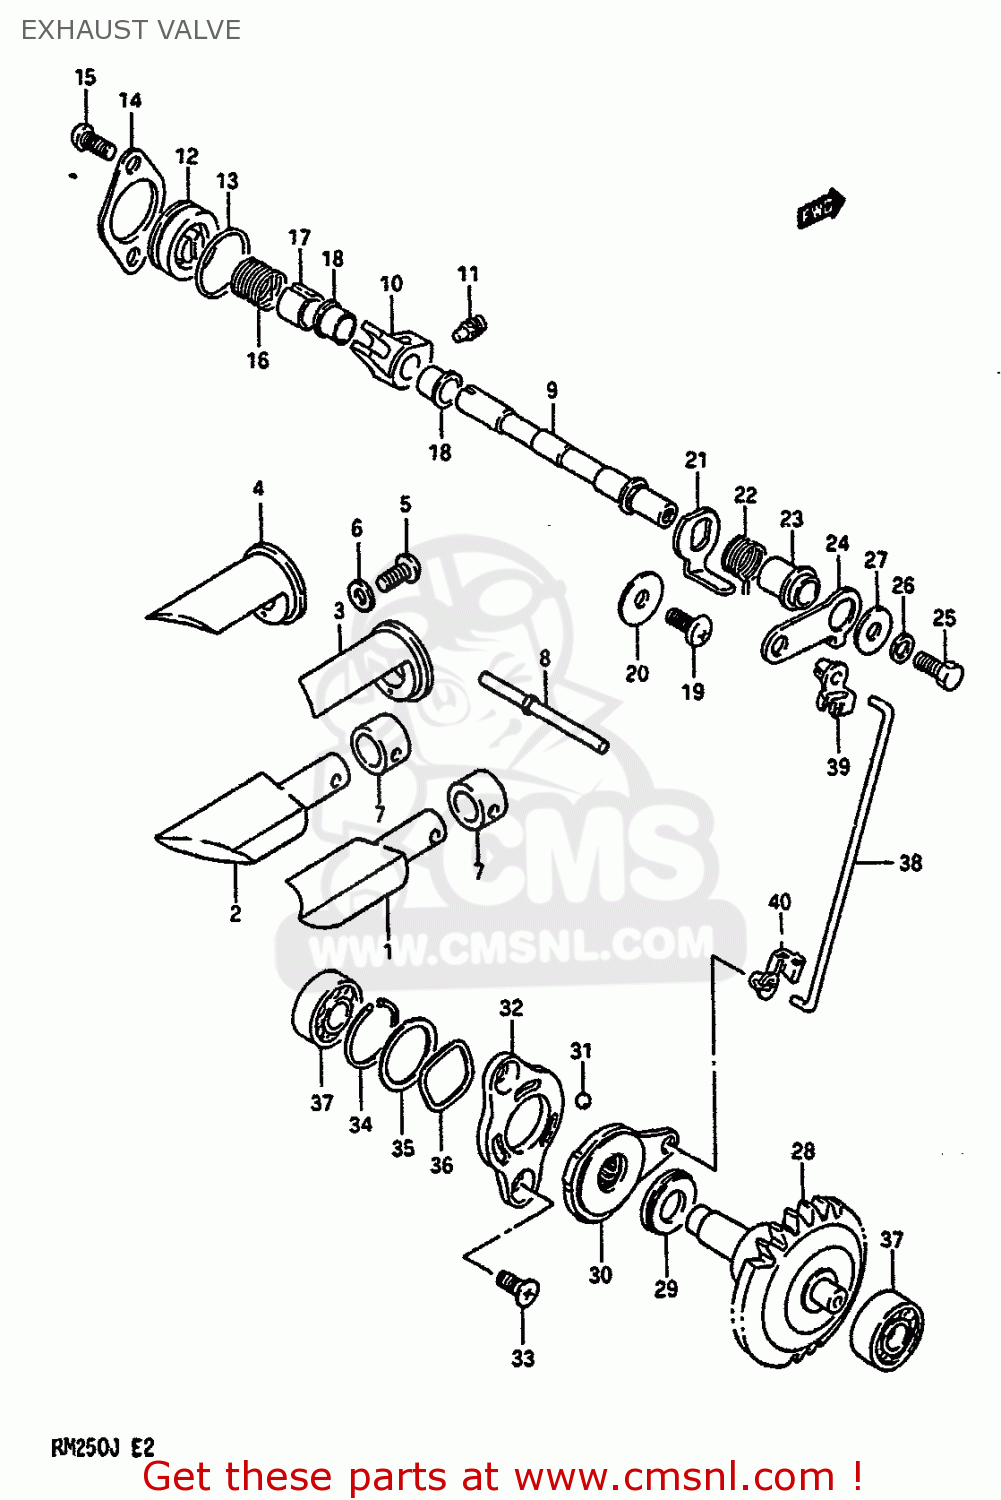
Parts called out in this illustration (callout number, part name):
1	VALVE,EXHAUST,R
2	VALVE,EXHAUST,L
3	GUIDE,EXHAUST VALVE,R
4	GUIDE,EXHAUST VALVE,L
5	SCREW
6	WASHER
7	HOLDER,EXHAUST VALVE
8	PIN,EXHAUST VALVE 48.5MM
9	SHAFT,EXHAUST VALVE
10	ARM,EXHAUST VALVE SHAFT
11	SCREW
12	CAP,EXHAUST VALVE
13	O RING(D:1.9,ID:22.6)
14	RETAINER,EXHAUST VALVE
15	SCREW
16	SPRING
17	SPACER,EXHAUST VALVE SPRING
18	BUSH
19	SCREW 6X12
20	WASHER
21	LEVER,EXHAUST VALVE NO
22	SPRING
23	SPACER,EXHAUST VALVE
24	LEVER,EXHAUST VALVE NO
25	BOLT
26	LOCK WASHER
27	WASHER (5.5X16X1.2)
28	GOVERNOR ASSEMBLY,EXHAUST
29	BEARING(10X22X2.8)
30	ACTUATOR,EXHAUST VALVE
31	BALL
32	STARTER,EXHAUST VALVE ACTUATOR
33	SCREW(5X10)
34	CIRCLIP
35	SHIM(19.1X25X0.3)
36	WASHER
37	BEARING(8X22X7)
38	ROD,EXHAUST VALVE
39	BUSH,EXHAUST VALVE ROD NO.1
40	BUSH,EXHAUST VALVE ROD NO.2
